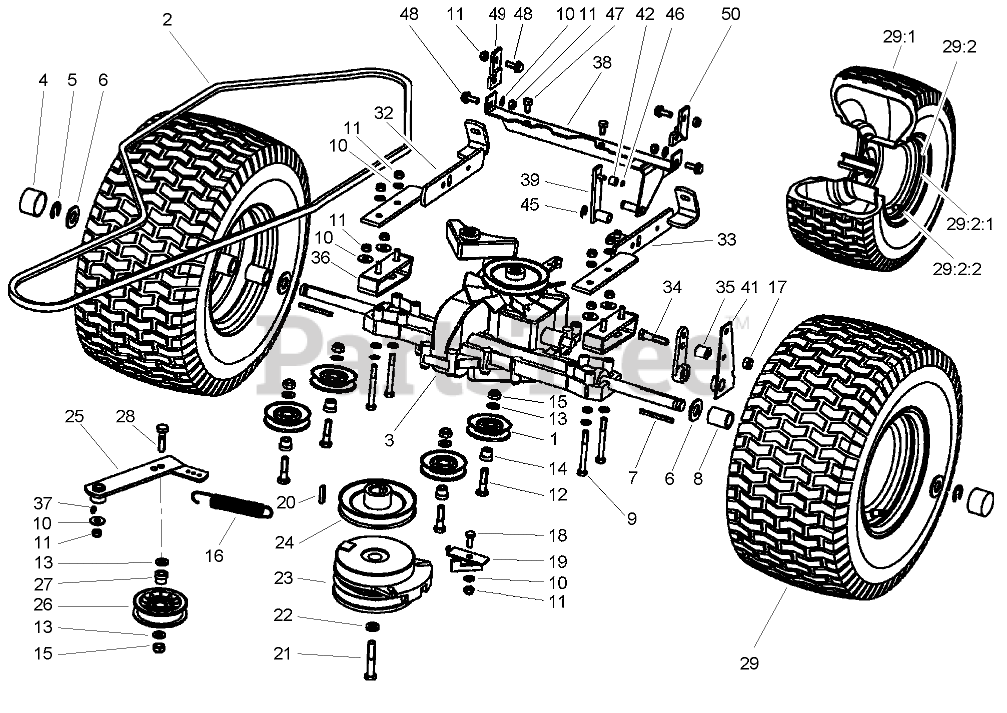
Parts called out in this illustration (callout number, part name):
1	PULLEY-IDLER
2	V-BELT-TRACTION
3	TRANSMISSION
4	CAP-HUB
5	CLIP-SPRING
6	WASHER
7	KEY-SQUARE
8	SPACER-AXLE
9	SCREW-HH
10	WASHER-PLAIN
11	NUT-LOCK, NI
12	SCREW-HH
13	WASHER-FLAT
14	BUSHING-IDLER
15	NUT-LOCK, NI
16	SPRING
17	NUT-LOCK, NI
18	SCREW-HH
19	RETAINER
20	KEY-SQUARE
21	SCREW-HH
22	WASHER-SPRING, BELLEVILLE
23	CLUTCH-ELECTRIC
24	PULLEY-ENGINE
25	ARM-IDLER
26	PULLEY-IDLER
27	BUSHING-IDLER
28	SCREW-HH
29	WHEEL AND TIRE ASM
29:1	TIRE
29:2	WHEEL ASM
29:2:1	RIM
29:2:2	Valve-Tire
32	Bracket-Right
33	Bracket-Left
34	SCREW-HH
35	SLEEVE
36	BRACKET-SUPPORT
37	FITTING-GREASE
38	Bar ASM
39	Arm-Switch
42	Roller
45	Stirrup
46	STIRRUP
47	SCREW-THREAD FORMING
48	SCREW-HEX
49	BRACKET-RIGHT
50	BRACKET-LEFT
